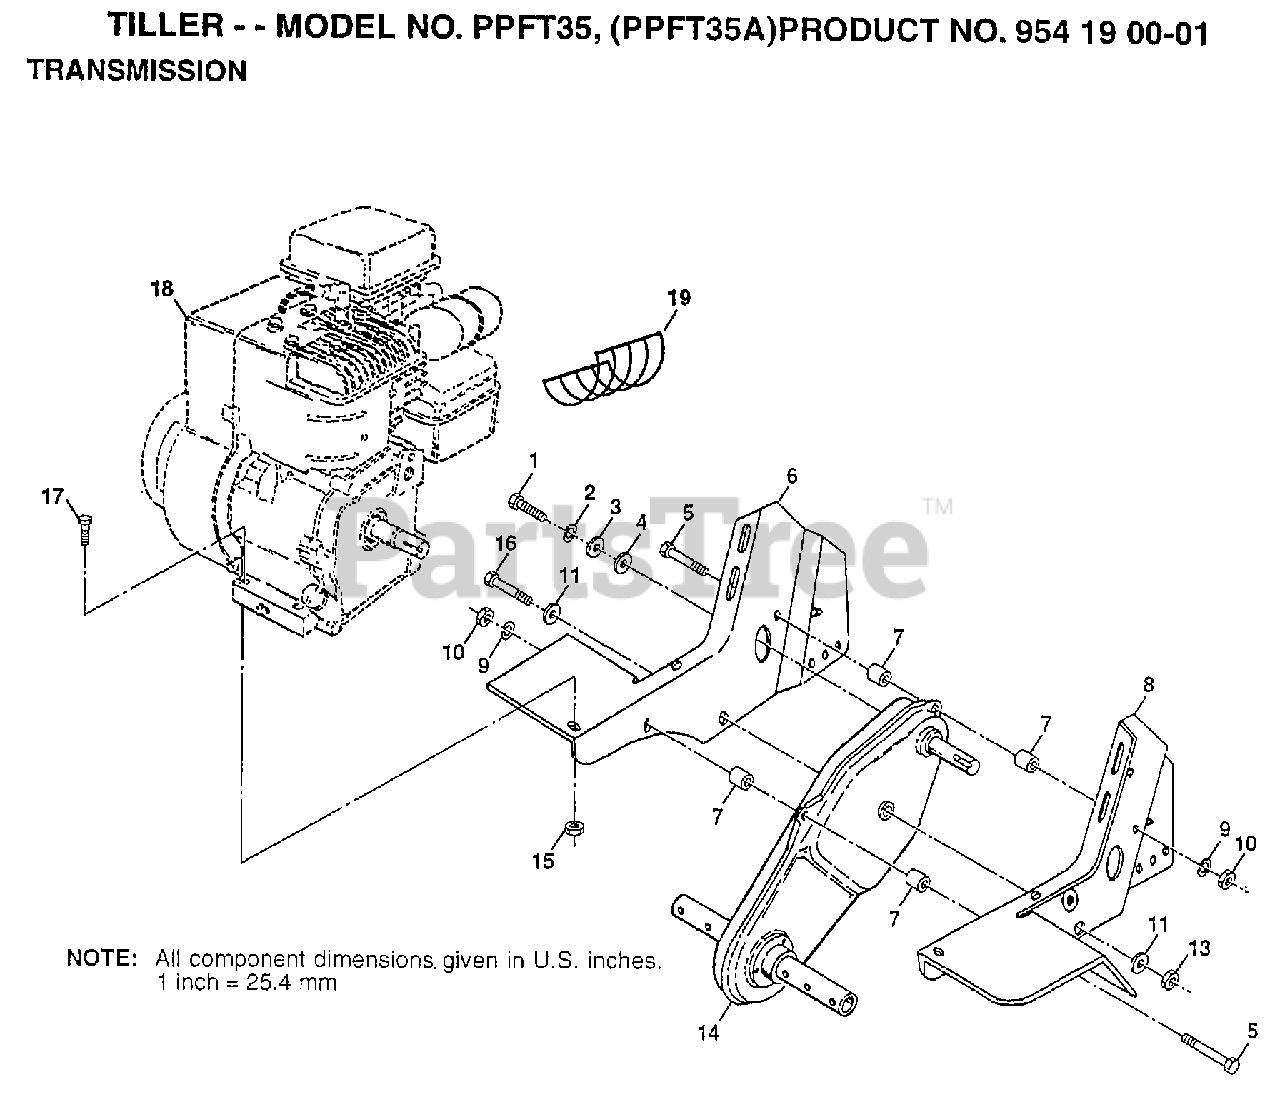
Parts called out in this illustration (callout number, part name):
1	BOLT, HEX 1/4-28 X 3/4 GR. 5
2	WASHER, LOCK 1/4
3	WASHER 9/32 X 1-1/4 X 16 GA.
4	WASHER 9/32 X 7/8 X 12 GA.
5	BOLT, HEX 5/16-18 X 2-3/4
11	WASHER 13/32 X 13/16 X 11 GA.
13	LOCKNUT
15	NUT, KEPS 5/16-18
16	BOLT, HEX 3/8-16 X 3-1/4
17	BOLT, HEX 5/16-18 X 1-1/2
